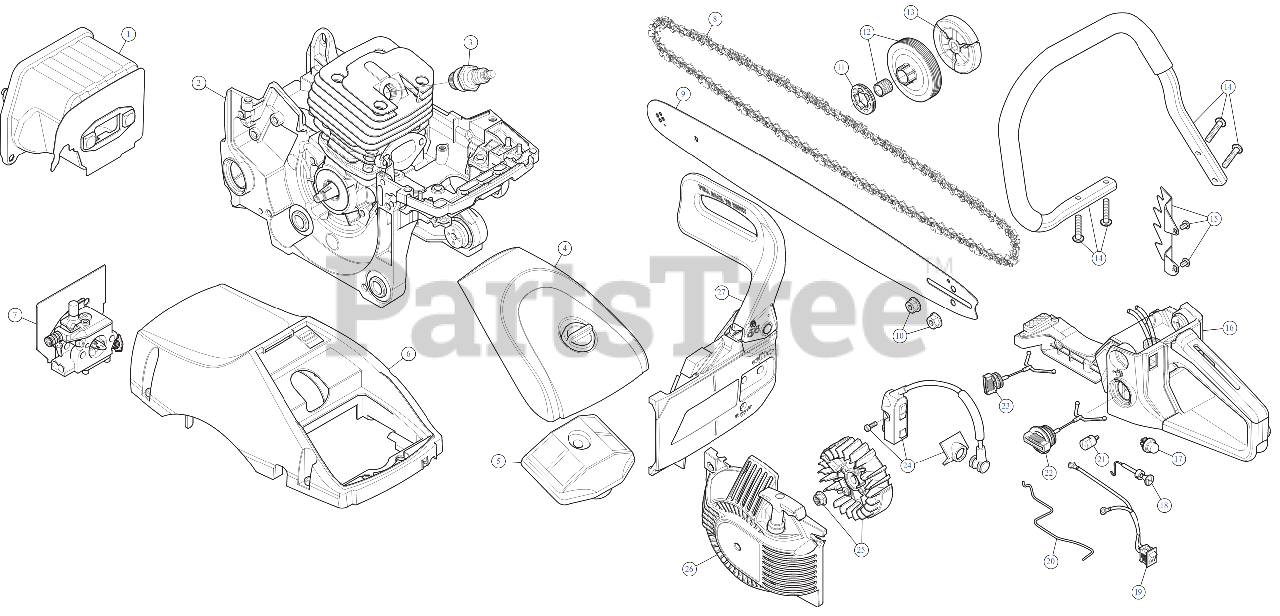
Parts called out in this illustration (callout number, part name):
1	MUFFLER ASSEMBLY
2	SHORT BLOCK 42CC YD4200.8-31000
3	SPARK PLUG:L8RTF YD4500-26200
4	AIR FILTER COVER ASSEMBLY
5	AIR FILTER W/SEAL
6	COVER
7	CARBURATOR
8	CHAIN: 16" TRILINK
9	CHAINSAW BAR 16" (OREGON)
10	BAR NUT M8
11	DRIVE SPROCKET
12	CLUTCH DRUM ASSEMBLY
13	CLUTCH ASSEMBLY
14	HANDLE ASSEMBLY
15	SPIKE PLATE W/HDW
16	FUEL HOUSING ASSEMBLY
17	PRIMER BULB YD2500-18410
18	CHOKE LEVER ASSEMBLY
19	SWITCH ASSEMBLY
20	THROTTLE ROD
21	FUEL FILTER YD4600-18034
22	FUEL CAP ASSEMBLY SRS
23	OIL CAP ASSEMBLY
24	MODULE
25	FLYWHEEL
26	RECOIL ASSEMBLY (SBD4216YD4216.8CM-25313)
27	BRAKE ASSEMBLY (SBD4216 YD4216.8CM-27724)
